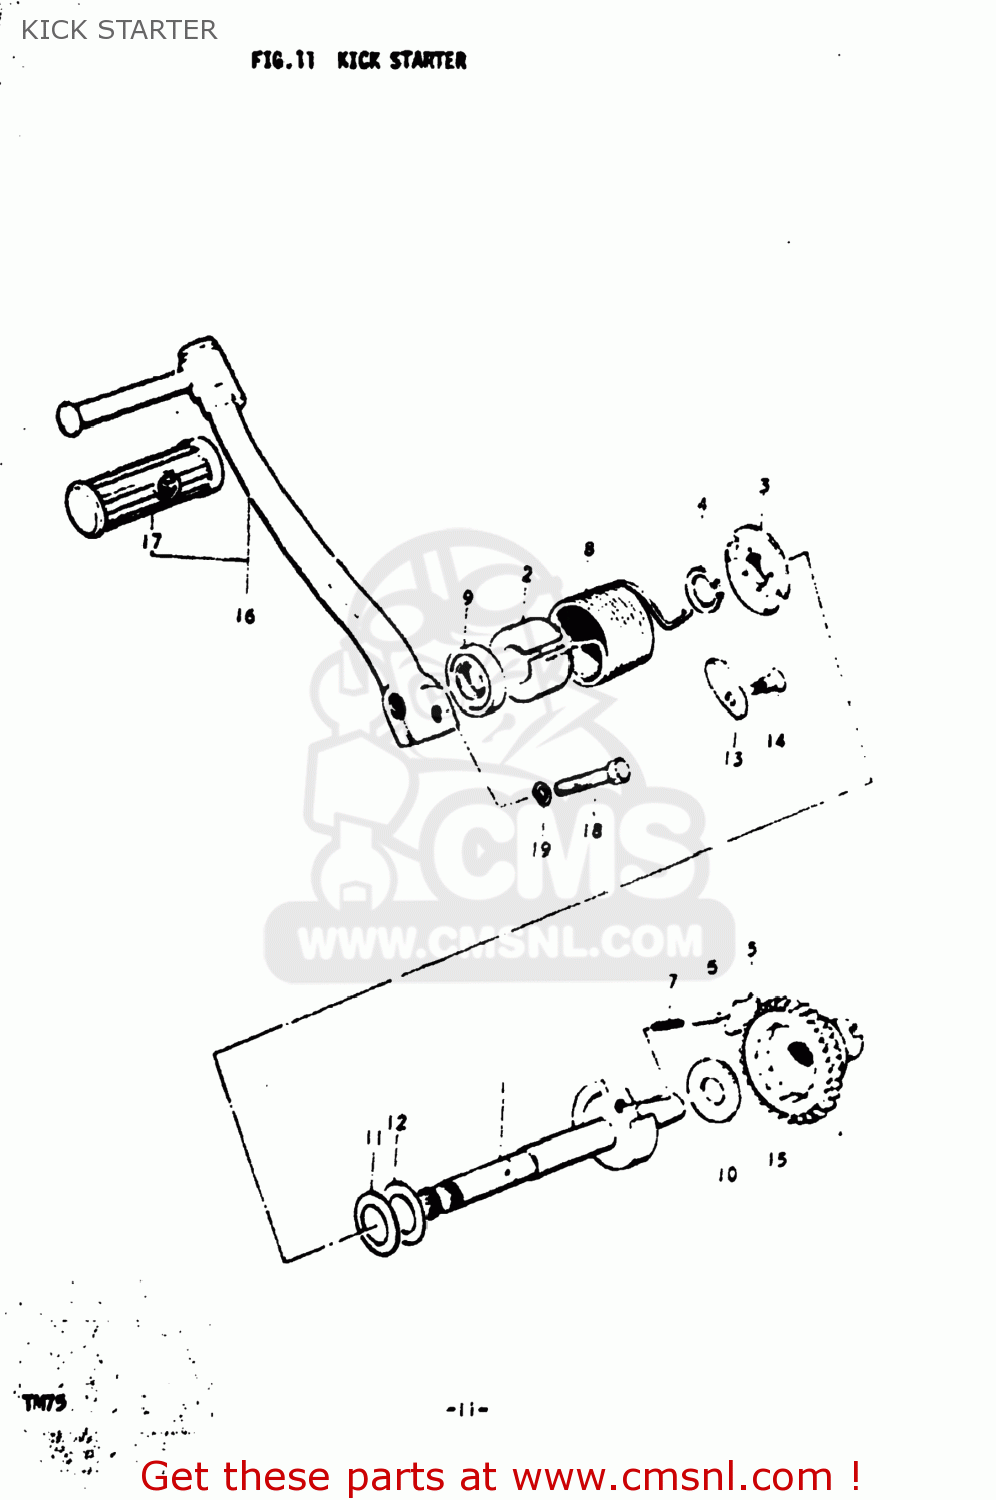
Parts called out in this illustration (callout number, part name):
1	SHAFT,KICK STARTER
2	GUIDE,KICK SHAFT SPRING
3	HOLDER,KICK STARTER SHAFT SPR
4	CIRCLIP
5	PAWL,KICK STARTER
6	PIN
7	SPRING
8	SPRING
9	SEAL,OIL(14X24X6)
10	WASHER
11	WASHER(14X29X0.8)
12	WASHER
13	LIFTER,KICK STARTER PAWL
14	SCREW(6X19)
15	GEAR,KICK STARTER DRIVE
16	LEVER ASSEMBLY,KICK STARTER
17	RUBBER,KICK STARTER PEDAL
18	BOLT
19	LOCK WASHER
